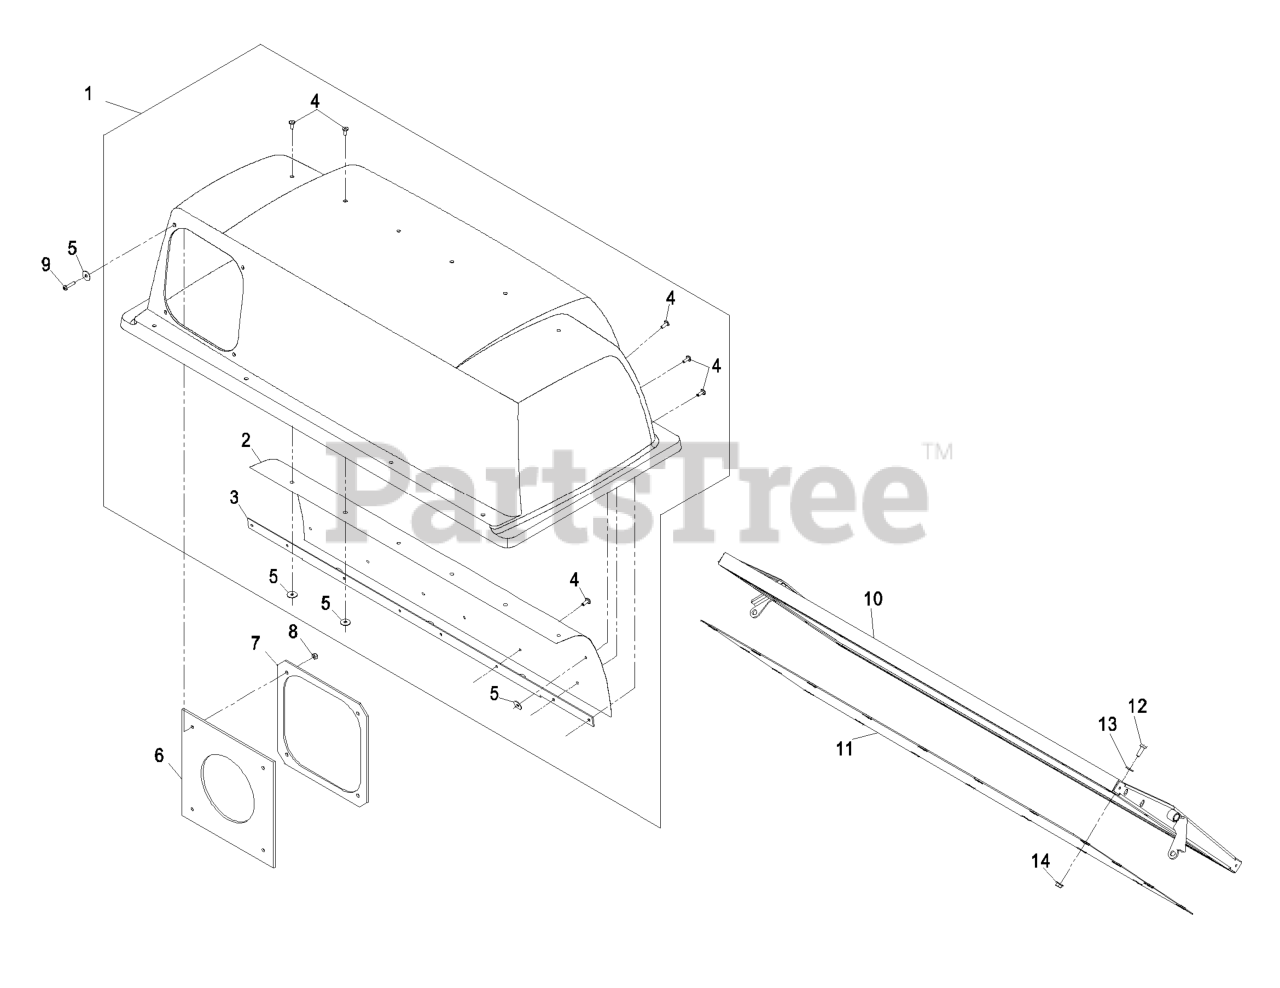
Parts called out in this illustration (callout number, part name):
1	ASM, HOOD
2	SCREEN-BAGGER
3	SUPPORT-SCREEN
4	RIVET-BLIND
5	WASHER-FLAT
6	SEAL-CHUTE
7	CLAMP-SEAL
8	NUT-LOCK, NI
9	SCREW-PPH
10	DOOR-FRAME
11	SCREEN-DOOR
12	SCREW-HH
13	WASHER-FLAT
